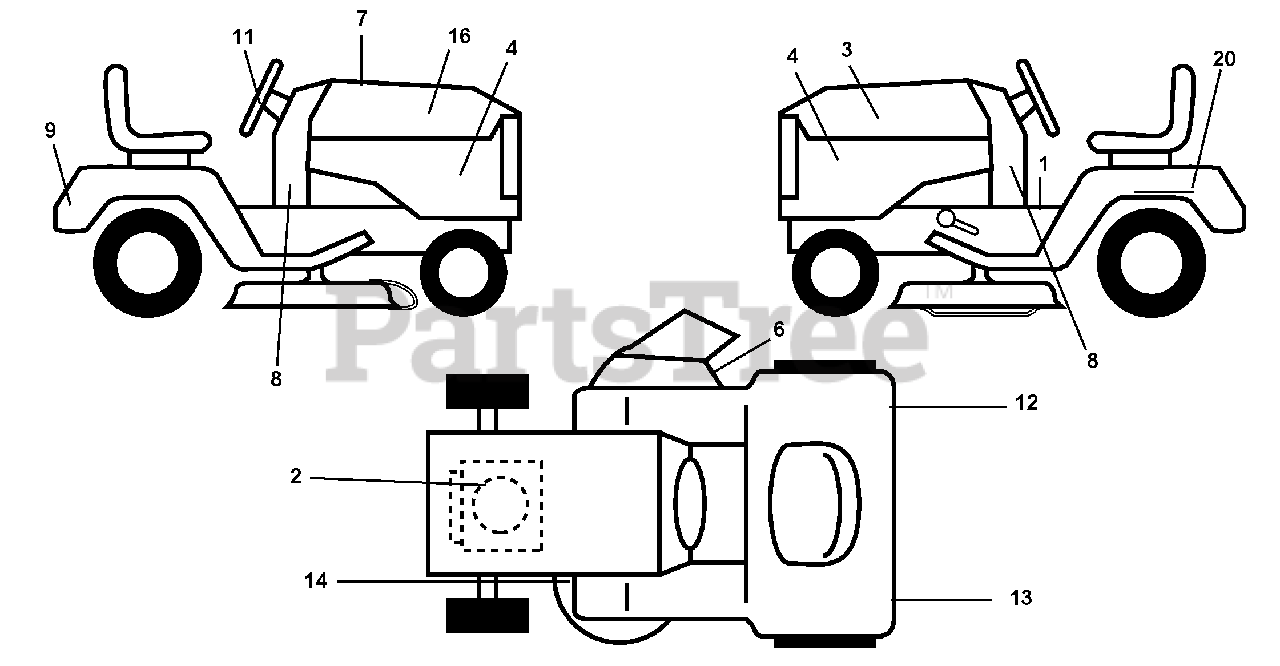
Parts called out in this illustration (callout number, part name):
1	Decal Oper
2	Decal Engine H.P.
3	Decal Hood LH
4	Decal Side Panel
6	Decal Warning, Keep Hand Away
7	Decal Replacement Parts
8	Decal LWRDASH
9	Decal Fender Logo
11	Decal Ins Strg Whl
12	Decal Fender SD RH
13	Decal Fender SD LH
14	Decal V-Belt Schematic
16	Decal Hood Rh
20	Decal Bat Dan/Psn
20	Pad Footrest LH
20	Pad Footrest RH
20	Decal Bypass
20	Manual Operator's E&F
20	Manual Parts
